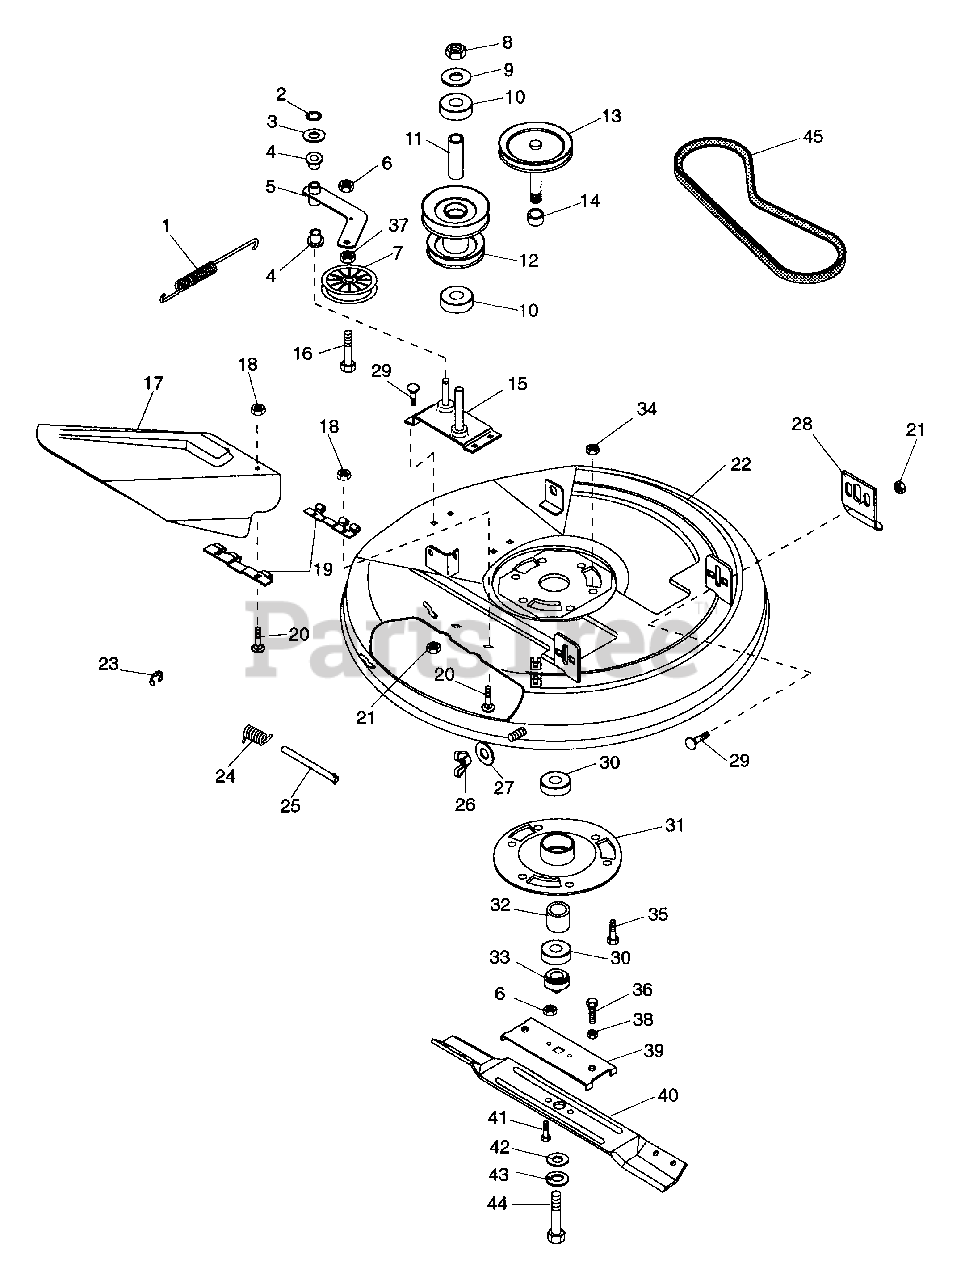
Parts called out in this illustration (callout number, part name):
1	SG-TENS .113X.812X7.00
2	RG-RTNG-EXT .500X.042 (E)
3	WSHR-FL-STL .505X.880X.072 PL
4	BSHG-FLG .500X.625X.187X.750FD
5	IDLER ARM
6	NUT-LK TOP .375-16 GR C YWZC
7	IDLER-FLAT 2.75 X .38 DAYCO
8	NUT-LK-NYL.625-18 PL
9	WSHR-FL-STL .640X1.005X.062 PL
10	BRG-BALL .625X1.375X.44
11	SPACER .647X.812X1.780
12	JACKSHAFT
13	MOWER SHEAVE 32"
14	SPACER .753X1.000X.660
15	MOUNT PLATE 32"
16	BLT-HEX .38-16X1.75 PL GR2
17	32" DEFLECTOR W/DECAL
18	NUT-LK-CTR .250-20 PL
19	HINGE PLATE
20	BLT-RDHDSQNK .25-20X.50 SHT PL
21	NUT-FLG. .312-18 PL
22	32" MOWER DECK W/DECALS
22	32" MOWER DECK ASSY COMPLETE
23	RG-RTNG-EXT .312X.025
24	SG-TORS .090X.37X.63
26	NUT-WING W/INSERT .312 - 18
27	WSHR-FL-STL .328X.875X.062 PL
28	MOWER ADJUSTMENT TAB
29	BLT-RDHDSQNK.31-18X.75GR5SHTPL
30	BRG-BALL .750X1.781X.61
31	SPINDLE HOUSING
32	SPACER .753X1.000X1.140
34	NUT-LK-CTR .375-16 GR A PL
35	BLT-HEX .38-16X.75 PL GR5
36	BLT-HEX .38-24X1.25 PL GR5
37	NUT-JAM .375-16 PL
38	NUT JAM .375-24 PL
39	BLADE TRAY WELDMT
40	32" BLADE
41	BLT-HEX .38-16X1.00 PL GR5
42	WSHR-FL-STL .505X1.140X.250
43	WSHR-LK .438X.133 HVY
44	BLT-HEX .44-20X1.75 PL GR5
45	V-BELT, 4L-WRAPPED
